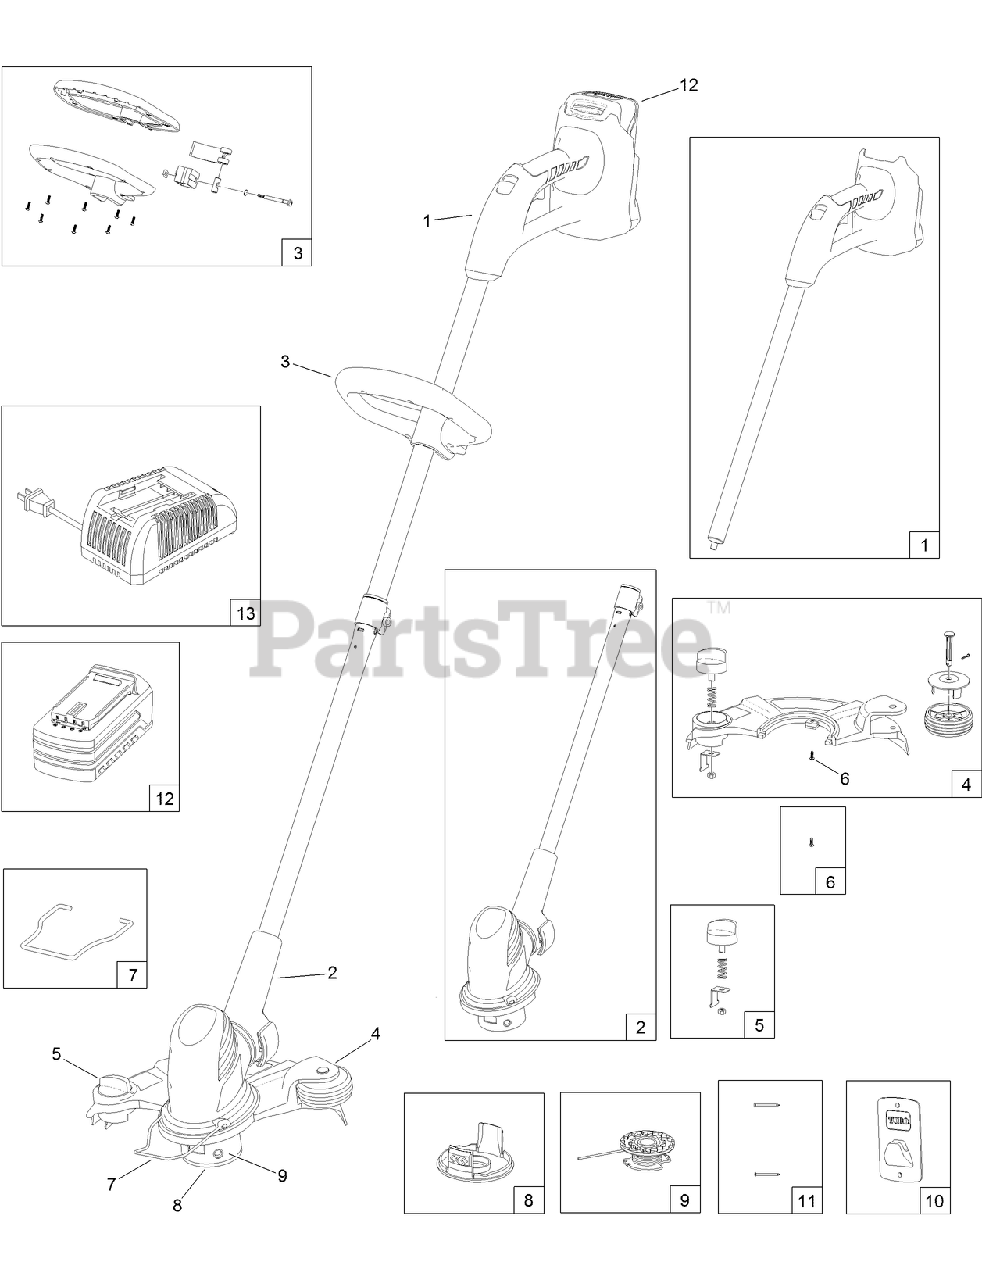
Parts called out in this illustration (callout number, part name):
1	HANDLE-UPPER
2	LOWER MOTOR HOUSING ASM
3	ASSIST HANDLE ASM
4	GRASS SHIELD ASM
5	KNOB-SAVER, POWER
7	CLIP-GUIDE, EDGER
8	CAP-RETAINER, SPOOL
9	SPOOL-TRIMMER, 12 INCH
10	BRACKET-MOUNT, WALL
12	BATTERY-LI-ION, 24V, 2.0AH
13	CHARGER-24V, LI-ION BATTERY
